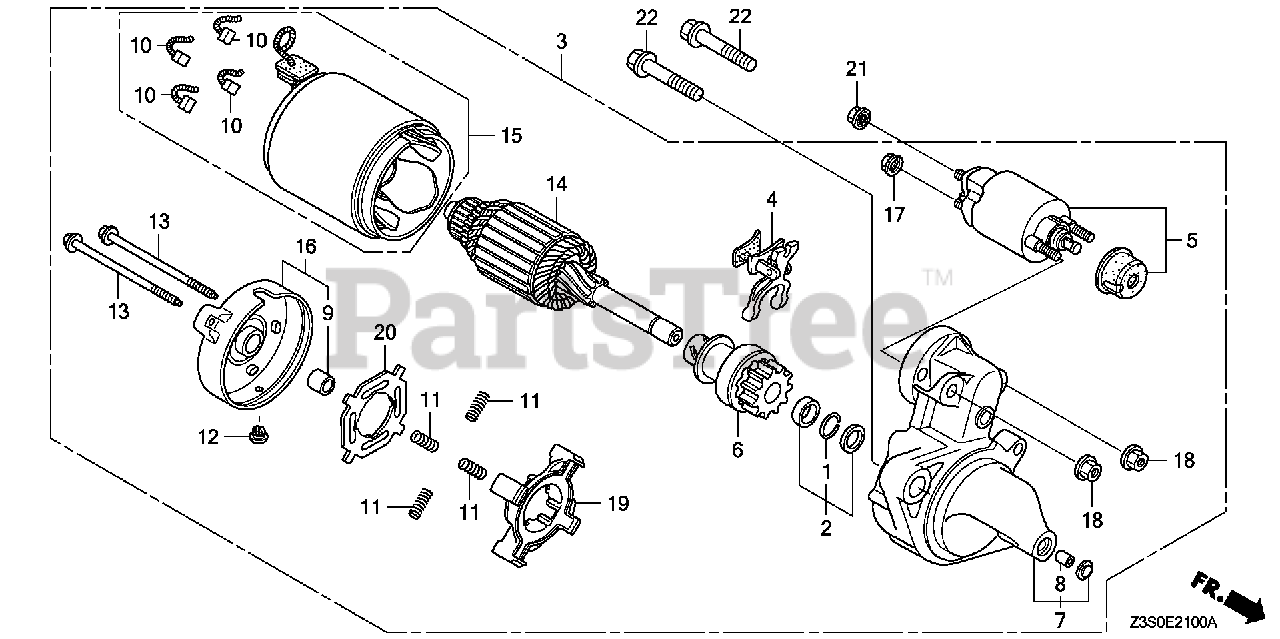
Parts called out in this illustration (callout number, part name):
1	RING, SNAP (DENSO)
2	COLLAR SET, CLUTCH STOP
3	STARTER MOTOR ASSY.
4	LEVER, PINION DRIVE
5	SWITCH ASSY., MAGNET
6	CLUTCH, OVERRUNNING
7	HOUSING, DRIVE SIDE
9	BEARING B
10	BRUSH
11	SPRING, BRUSH
13	BOLT, THROUGH
16	FRAME, COMMUTATOR END
17	NUT, HEX. (8MM)
18	NUT, FLANGE (5MM)
19	HOLDER, BRUSH
20	INSULATOR, BRUSH HOLDER
21	NUT-WASHER (8MM)
22	BOLT, FLANGE (10X40)
